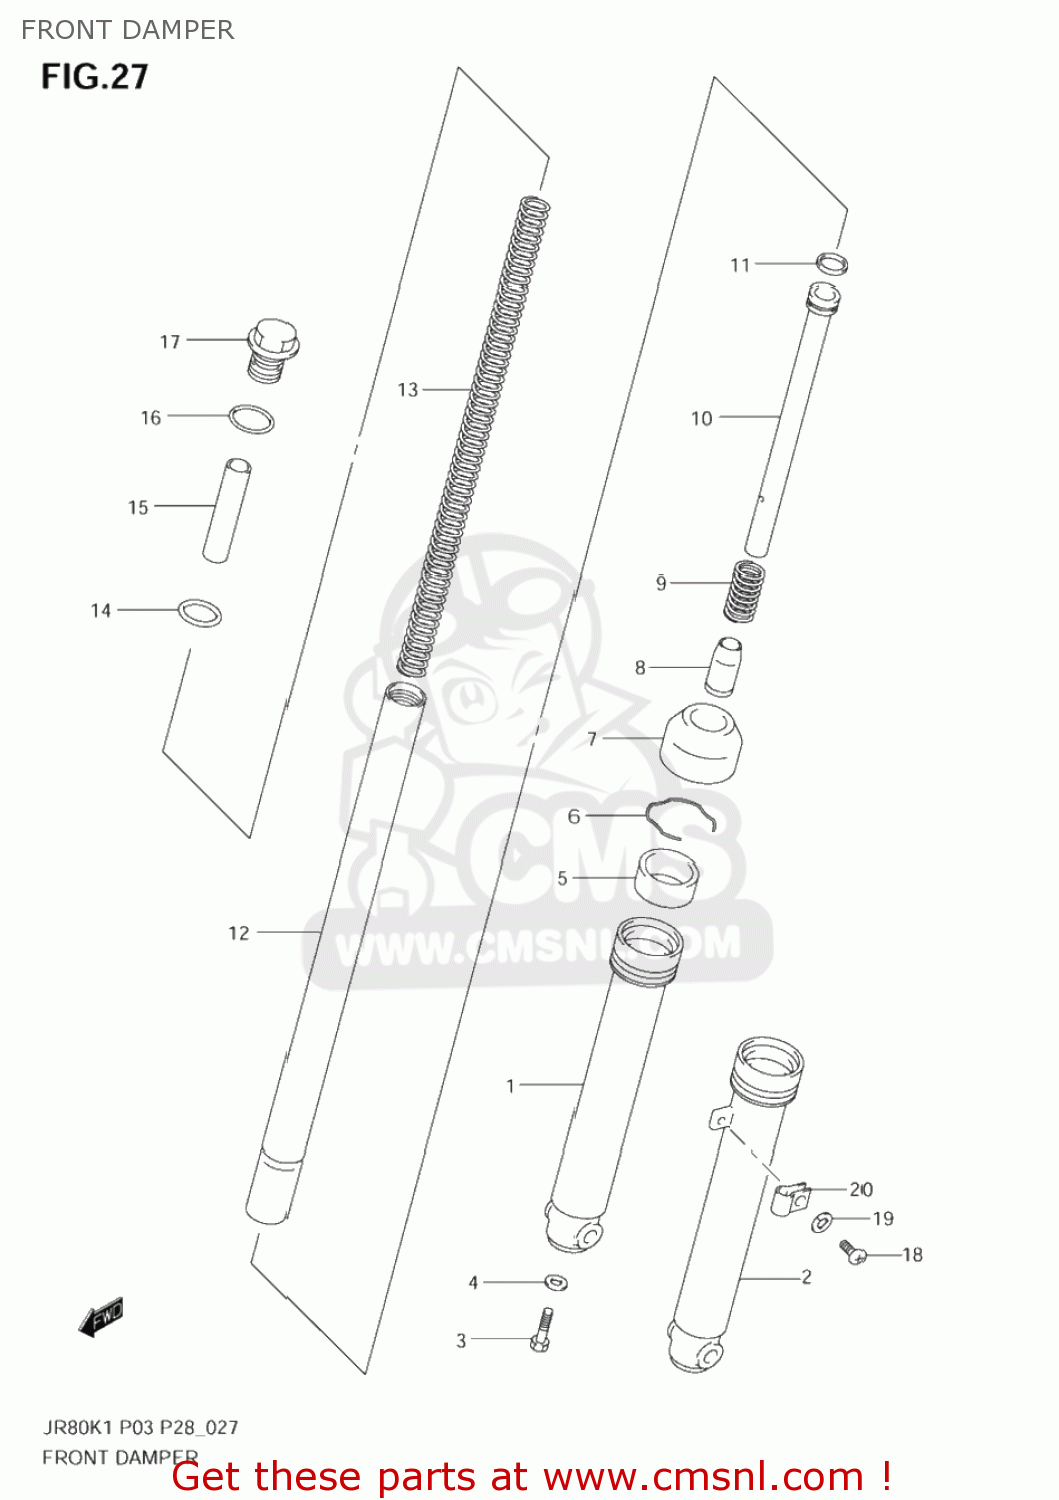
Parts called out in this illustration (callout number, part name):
1	TUBE,OUTER,R
2	TUBE,OUTER,L
3	BOLT(8X27)
4	GASKET (NAS)
5	SEAL,OIL
6	RING,OIL SEAL STOPPER
7	DUST SEAL
8	PIECE,OIL LOCK
9	SPRING,REBOUND
10	CYLINDER,FR FORK
11	RING,PISTON
12	TUBE,INNER
13	SPRING
14	JOINT,SPRING
15	SPACER,SPRING
16	O RING(D:2.4,ID:17.8)
17	CAP
18	SCREW
19	WASHER,LOCK
20	CLIP,FR BRAKE CABLE
